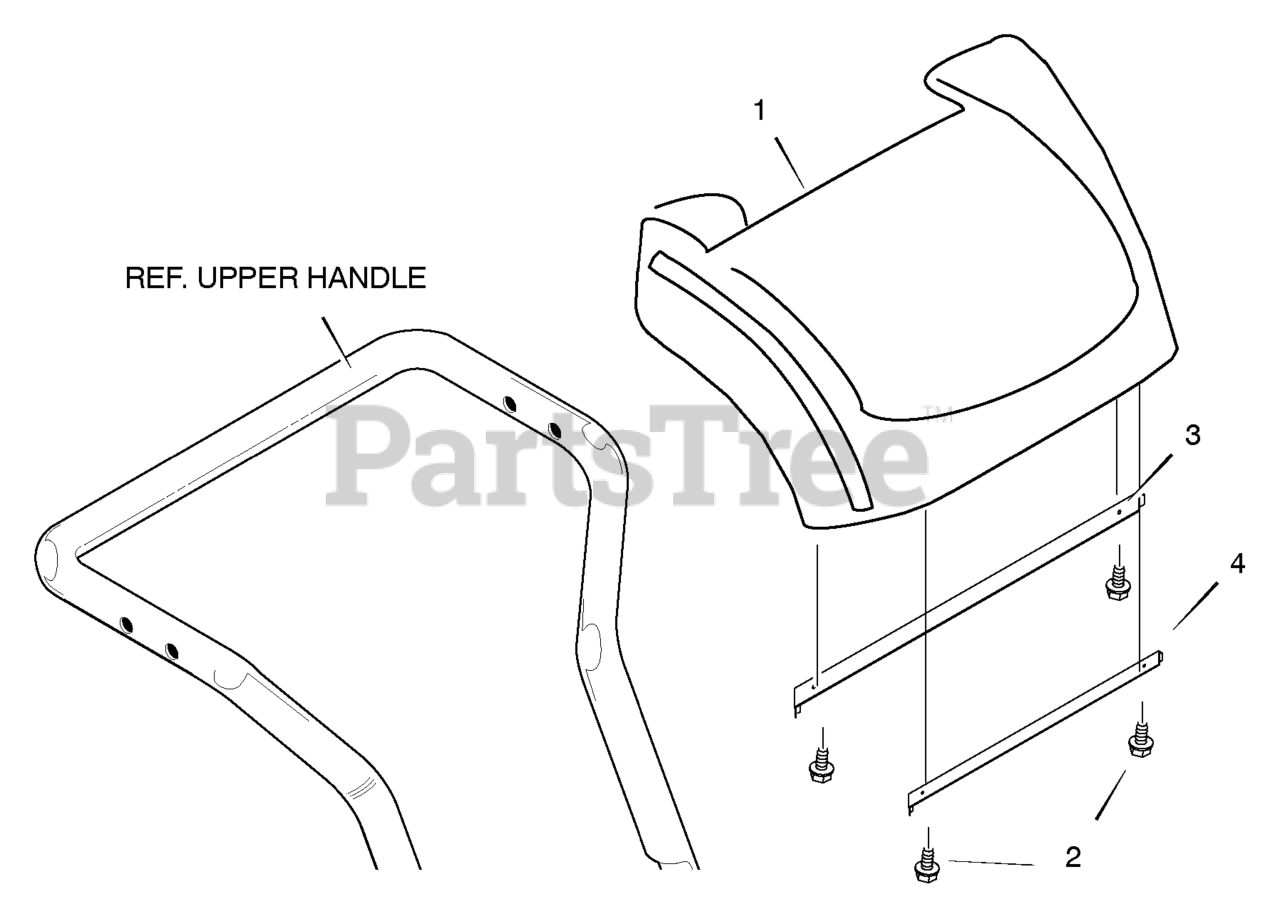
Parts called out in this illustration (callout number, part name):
1	PANEL, CONSOLE
2	SCREW, 10 x 0.62
3	BRACKET, HANDLE COVER -TOP
4	BRACKET, HANDLE COVER -BOTTOM
